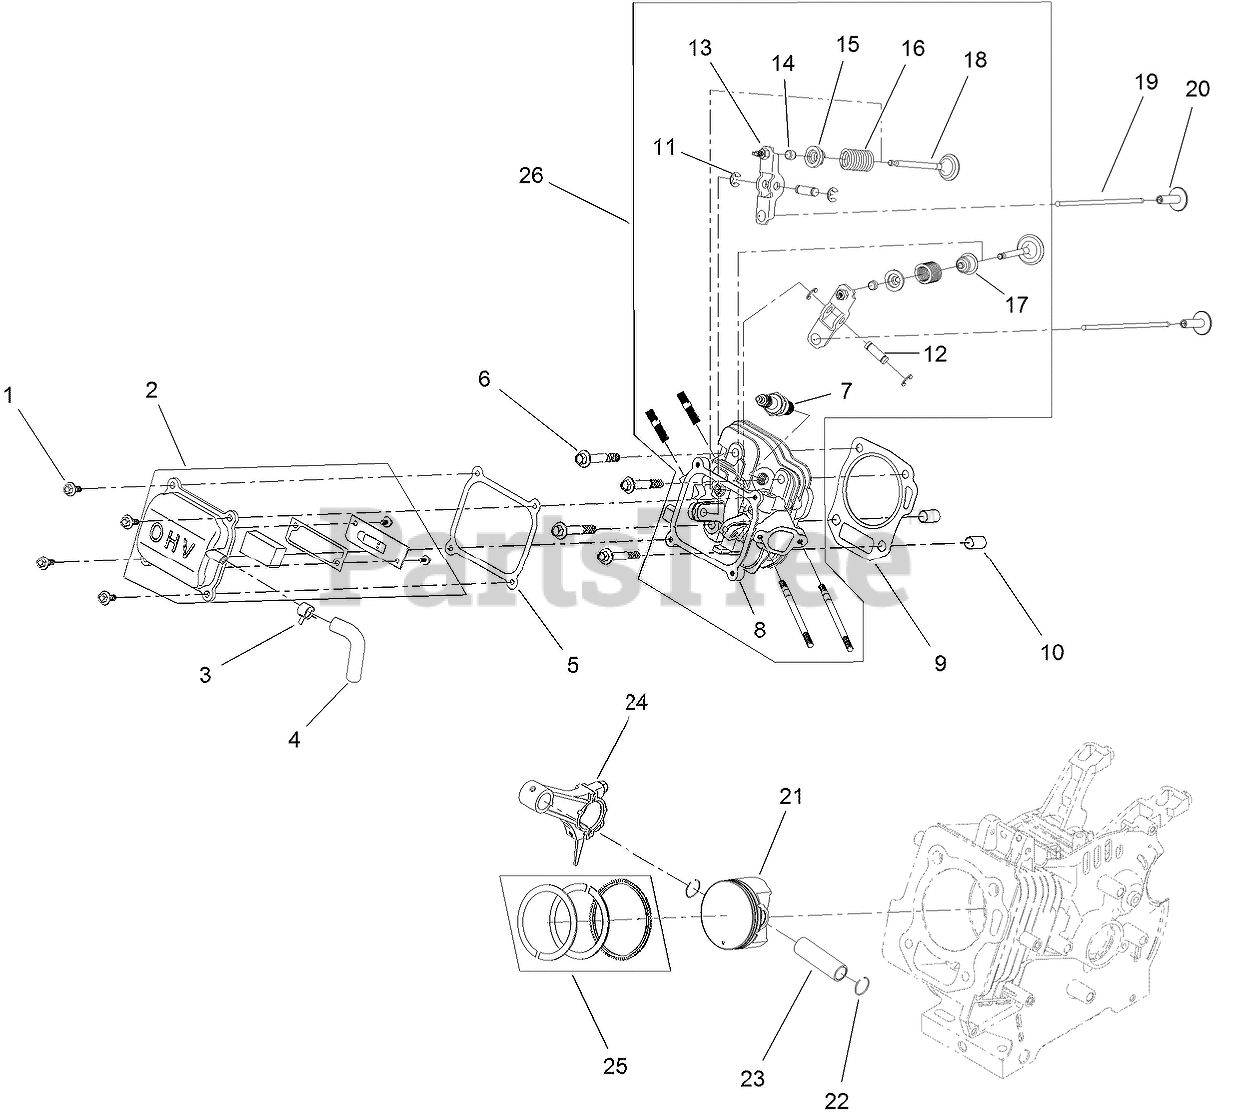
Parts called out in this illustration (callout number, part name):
1	SCREW-HHF
2	VALVE COVER ASM
3	CLAMP-HOSE
4	TUBE-BREATHER
5	GASKET-COVER, VALVE
6	SCREW-FLANGE
7	SPARK PLUG
8	HEAD-CYLINDER
9	GASKET-HEAD
10	PIN-DOWEL
11	E-CLIP
12	PIN-ARM, ROCKER
13	ROCKER ARM ASM
14	ROTATOR-VALVE
15	RETAINER-SPRING, VALVE
16	SPRING-VALVE
17	SEAL-STEM, VALVE
18	SET-VALVE
19	ROD-PUSH
20	TAPPET-VALVE
21	PISTON
22	CLIP-PIN, PISTON
23	PIN-PISTON
24	CONNECTING ROD ASM
25	SET-RING, PISTON
26	COMPLETE HEAD ASM
